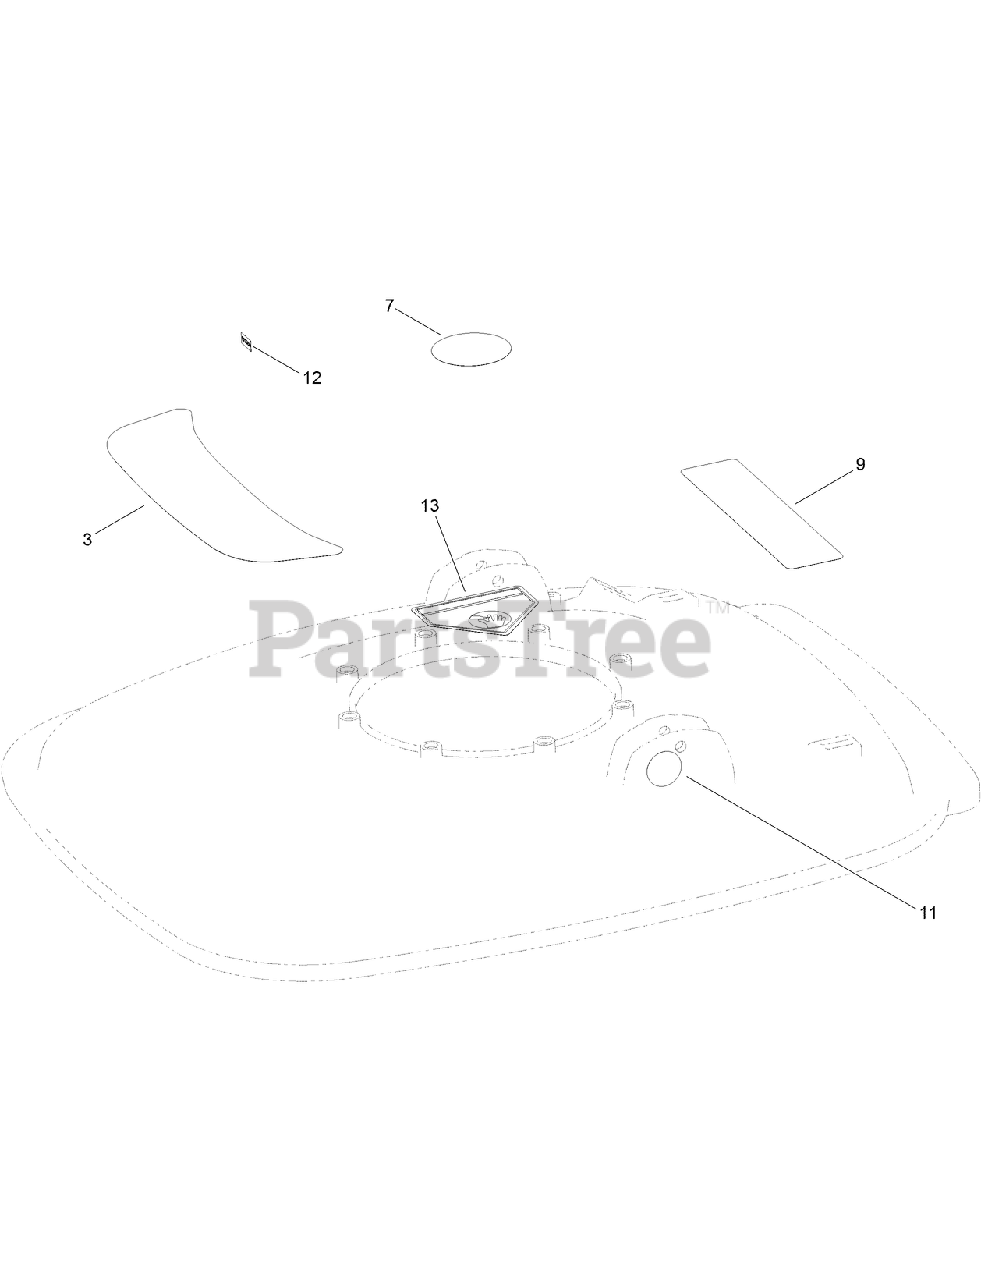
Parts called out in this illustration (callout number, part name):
3	DECAL-HOVER PRO, 500 SERIES
7	DECAL-ENGINE
9	DECAL-WARNING
11	DECAL
12	DECAL-STOP
13	DECAL-DANGER
